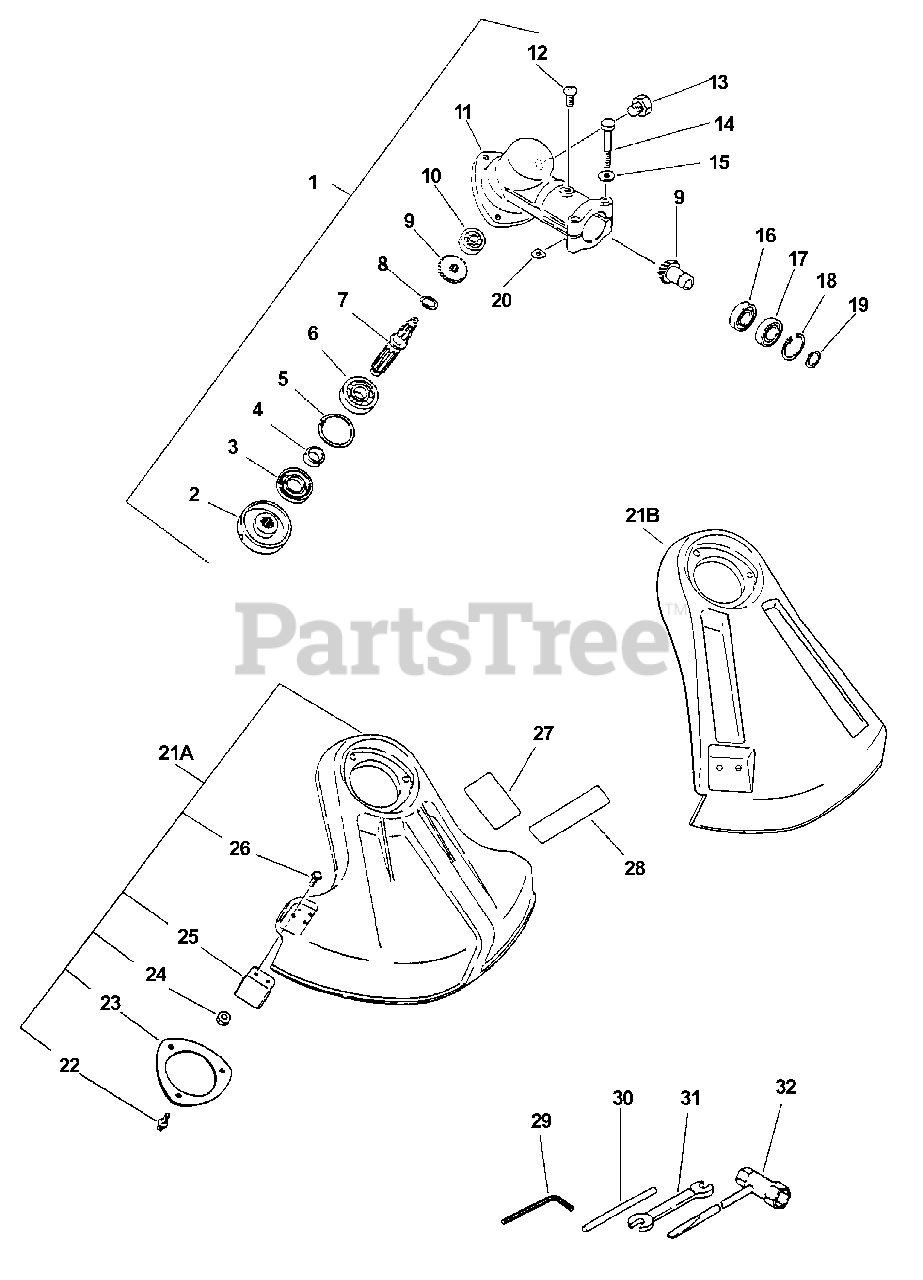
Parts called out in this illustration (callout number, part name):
1	GEAR CASE ASSY
2	PLATE, ADAPTOR - UPPER
3	SEAL, OIL 22
4	SPACER 11.8×15×9
5	RING, SNAP Ø32
6	BEARING, BALL - 6201 C3
7	SHAFT, GEAR
8	RING, SNAP Ø10
9	GEAR SET
10	BEARING, BALL 609
11	HOUSING, GEAR CASE
12	SCREW 5×10
13	BOLT 8×8 SP
14	BOLT 5×35 SP
15	WASHER, FLAT 5.5×10×0.8
16	BEARING, BALL 6900
17	BEARING, BALL 6900Z
18	RING, SNAP Ø22
19	RING, SNAP Ø10
21A	DEBRIS SHIELD ASSY
21B	DEBRIS SHIELD KIT
22	SCREW 5×16
23	PLATE, SHIELD Ø49.5 MM
24	NUT M5
25	CUTTER, LINE
26	SCREW 5×16
27	LABEL, CAUTION
28	LABEL, ECHO
29	WRENCH, ALLEN 4 MM
30	TOOL, LOCKING 5×120 MM
31	SPANNER 8×10
32	T-WRENCH 17x-19 L200
